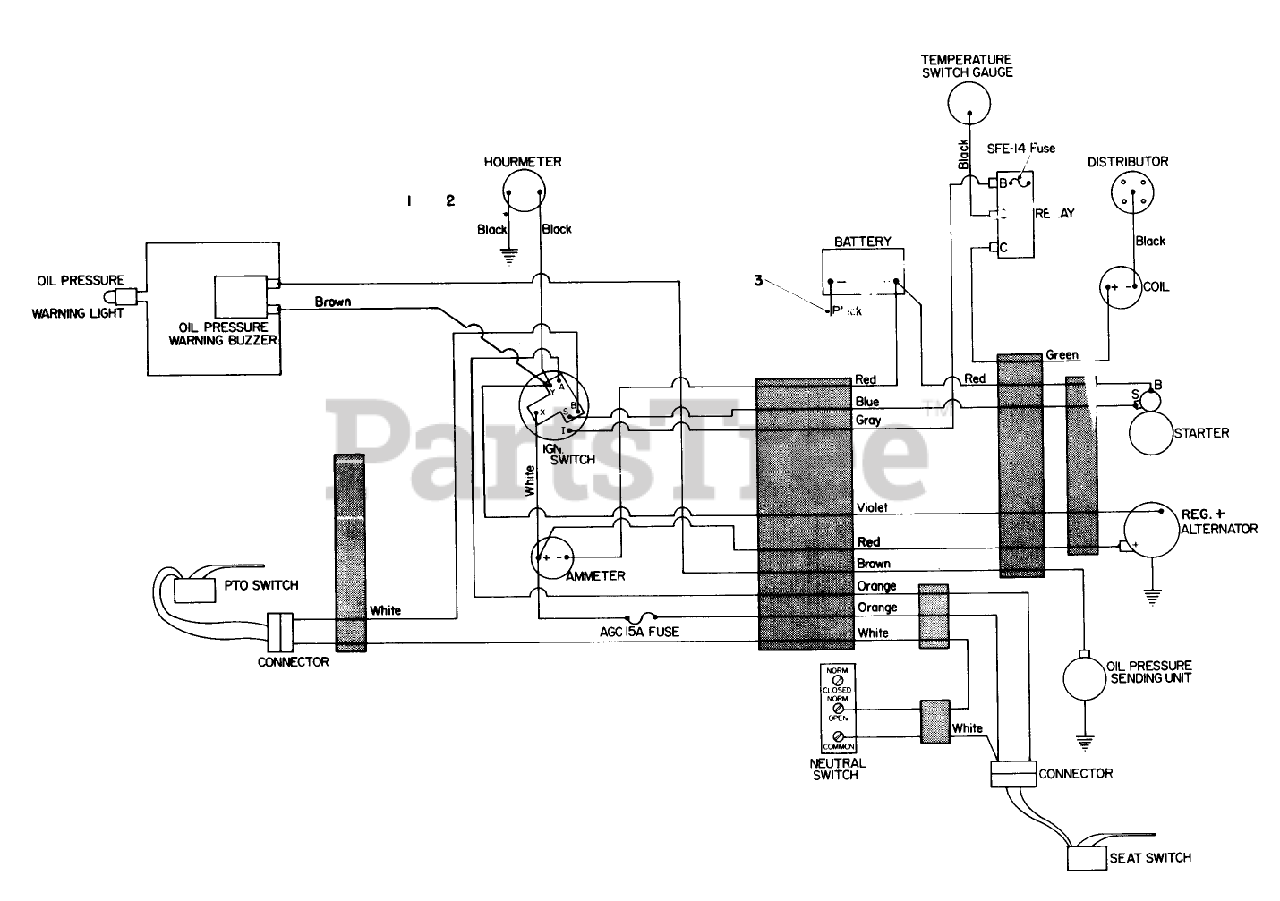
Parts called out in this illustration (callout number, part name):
1	WIRE HARNESS
2	Wire Harness
3	Cable Ground
